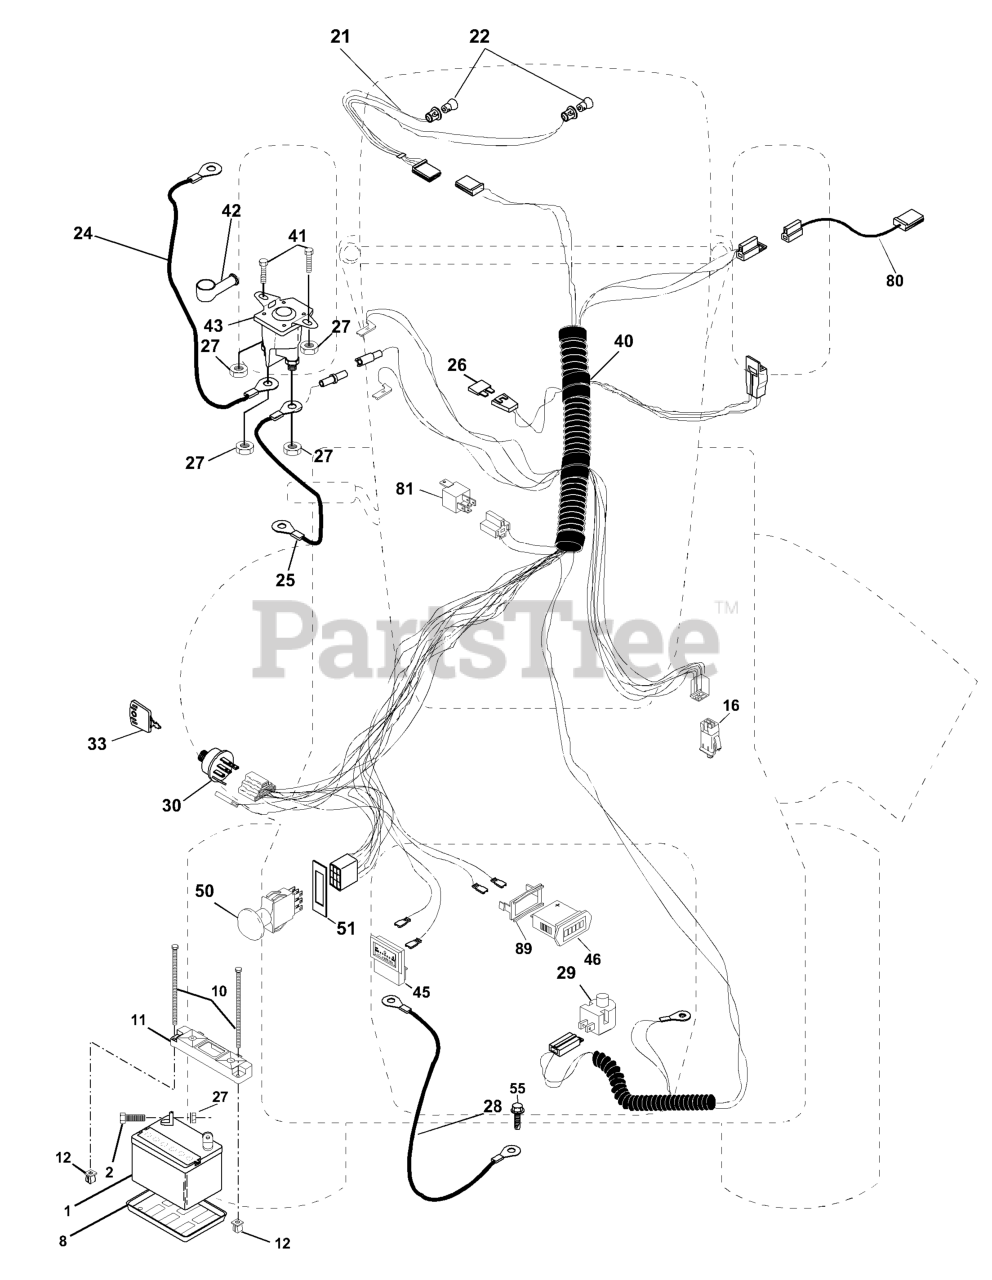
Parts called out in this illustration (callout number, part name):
1	BATTERY 12V .35 AMP
2	BOLT.HEX.1/4.X.3/4.DICHROMATE
8	BATTERY TRAY T
10	BOLT 1/4-20 X 7.5
11	BATTERY HOLDDOWN FRONT MOUNT
12	NUT, PUSH NYLON 1/4" BATTERY
16	SWITCH INTERLOCK
20	NUT
24	BATTERY CABLE GT
25	CABLE BATTERY 6 GA 22" W/16W
26	FUSE 15 AMP
27	NUT
28	CABLE GROUND 6 GA 21" 90T BLK
29	PLUNGER SWITCH (COLOR:OLIVE)
30	SWITCH IGN
33	KEY MLD GEN DELTA
40	HARNESS IGN.
41	BOLT
42	TERMINAL COVER
43	SOLINOID
46	HOUR METER
50	PTO SWITCH
51	FRAME RETAINING RING
55	Screw Thdrol 5/16-18 x 1-1/2 Tyt
80	HARNESS, CLUTCH
81	RELAY.ASSY.T
89	BRACKET SNAP-IN HOURMETER
